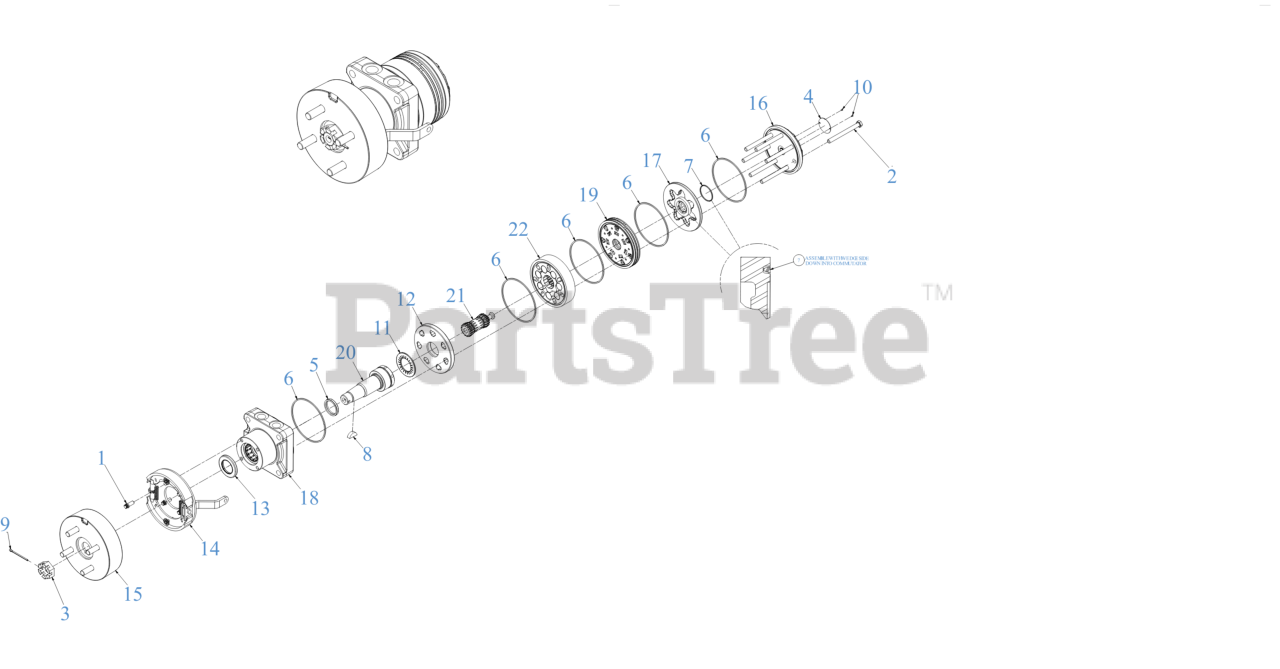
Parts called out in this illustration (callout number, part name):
1	SCREW-CAP (QTY 4)
2	SPECIAL BOLT 3/8-24 UNF-A2
3	HEX NUT 1-20 UNEF-28
4	IDENTIFICATION TAG
5	SHAFT SEAL
6	SEAL RING (BUNA)
7	COMMUTATOR SEAL
8	WOODRUFF KEY
9	COTTER PIN
11	THRUST BEARING
12	WEAR PLATE
13	DIRT & WATER SEAL
14	BRAKE ASSEMBLY
15	DRUM-4 BOLT BRAKE
17	COMMUTATOR ASSEMBLY
18	HOUSING ASSEMBLY
20	COUPLING SHAFT
22	ROTOR ASSEMBLY
